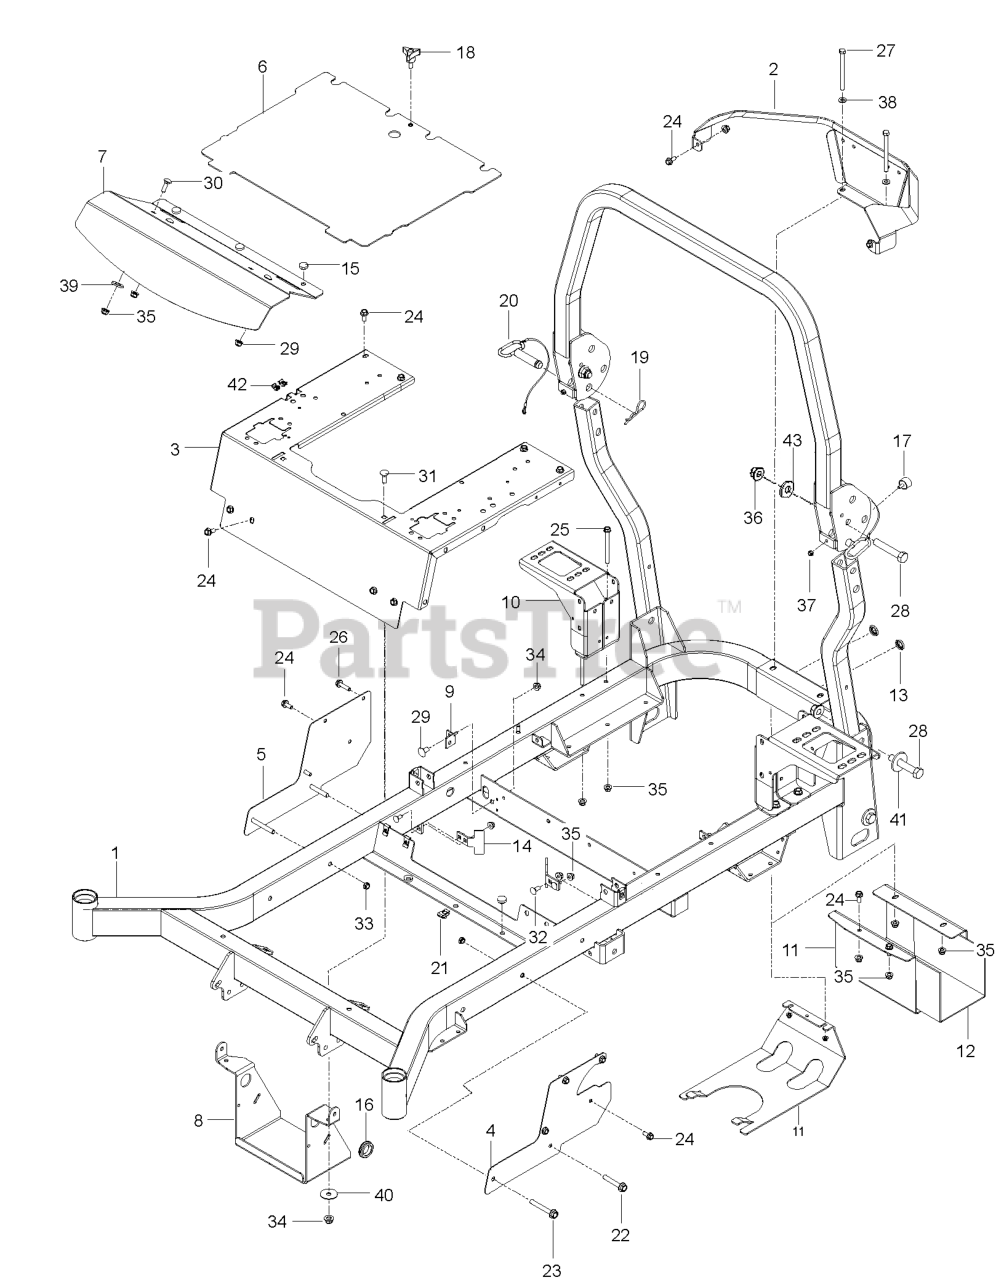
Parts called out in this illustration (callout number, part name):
1	KIT.FRAME.W/DECALS.X668
2	GUARD.PNT.REAR.MZ.GRAY
3	SUPPORT.PNT.SEAT.CONTROL.ORNG
4	BRACKET SIDE, LT ORANGE
5	BRACKET SIDE, RT ORANGE
6	PLATE, FLOOR W/DECALS
7	PLATE, FOOTREST
8	BRACKET BATTERY BLACK MS-431
8	BRACKET.PNT.BATTERY.BLK
9	BRACKET.DAMPENER.BLACK
10	MOUNT, TANK, ZT BLK
11	SHIELD.MUFFLER.BLACK
11	Husqvarna TBD
12	HEAT SHIELD
13	CAP.PLUG.BP-1.BLACK
14	STOP, DECK, EZ+
15	GROMMET, BUMPER
16	RUBBER GROMMET
17	HHFS 3/8-16 X 2-3/4 GR5 ZD
17	BUMPER, MALE STUD, 1/4-20
18	KNOB W/STUD
19	PIN HAIR .148 X 2-15/16 #210
19	HHFS 5/16-18 X 3/4
20	PIN, ROPS
20	HHFS 3/8-16 X 2.5 GR 5 ZD
21	U-CLIP 5/16-18 NUT RETAINER
22	HHFS 3/8-16 X 2.5 GR 5 ZD
22	HHFS 5/16-18 X 1.25 TPBLT GD 5
23	HCS 5/16C X 4
23	HHFS 3/8-16 X 2-3/4 GR5 ZD
24	HHFS 5/16-18 X 3/4
24	RHSNB 3/8-16 X 3/4 GR 5 BLK ZN
25	BOLT.HEX.FLNG.5/16-18X3.75
25	BOLT
26	BOLT
26	HHFS 5/16-18 X 1.25 TPBLT GD 5
27	NUT HEX 3/8-16 NYLON, THIN
27	HCS 5/16C X 4
28	5/8-11 X 3-1/2 HHB GRADE 5
28	BOLT.HEX.FLNG.5/16-18X3.75
29	NUT 3/8-16 HEX FLG NYLOC ZD
29	RP BOLT 5/16-18 X3/4 ZN/YEL GR
30	5/16-18 NYLOC FLANGE NUT
30	RHSNB 5/16C X 1
31	RHSNB 3/8C X 1
32	BOLT 5/16C X 3/4" CARRIAGE
32	WASHER
33	NUT HEX 3/8-16 NYLON, THIN
33	WASHER 1/2" FLAT
34	NUT 3/8-16 HEX FLG NYLOC ZD
35	5/16-18 NYLOC FLANGE NUT
36	NUT 5/8-11 FLG NYLOC ZD
37	LOCKNUT.NYLOC.1/4-20
37	NUT.1/4-20.HEX.NYLOC.ZD
38	WASHER
39	WASHER 1/2" FLAT
40	WASHER.13/32X1-1/2X16GA
41	WASHER, 5/8 FLAT
42	U-CLIP 5/16-18 NUT RETAINER
43	WASHER, 5/8 FLAT
